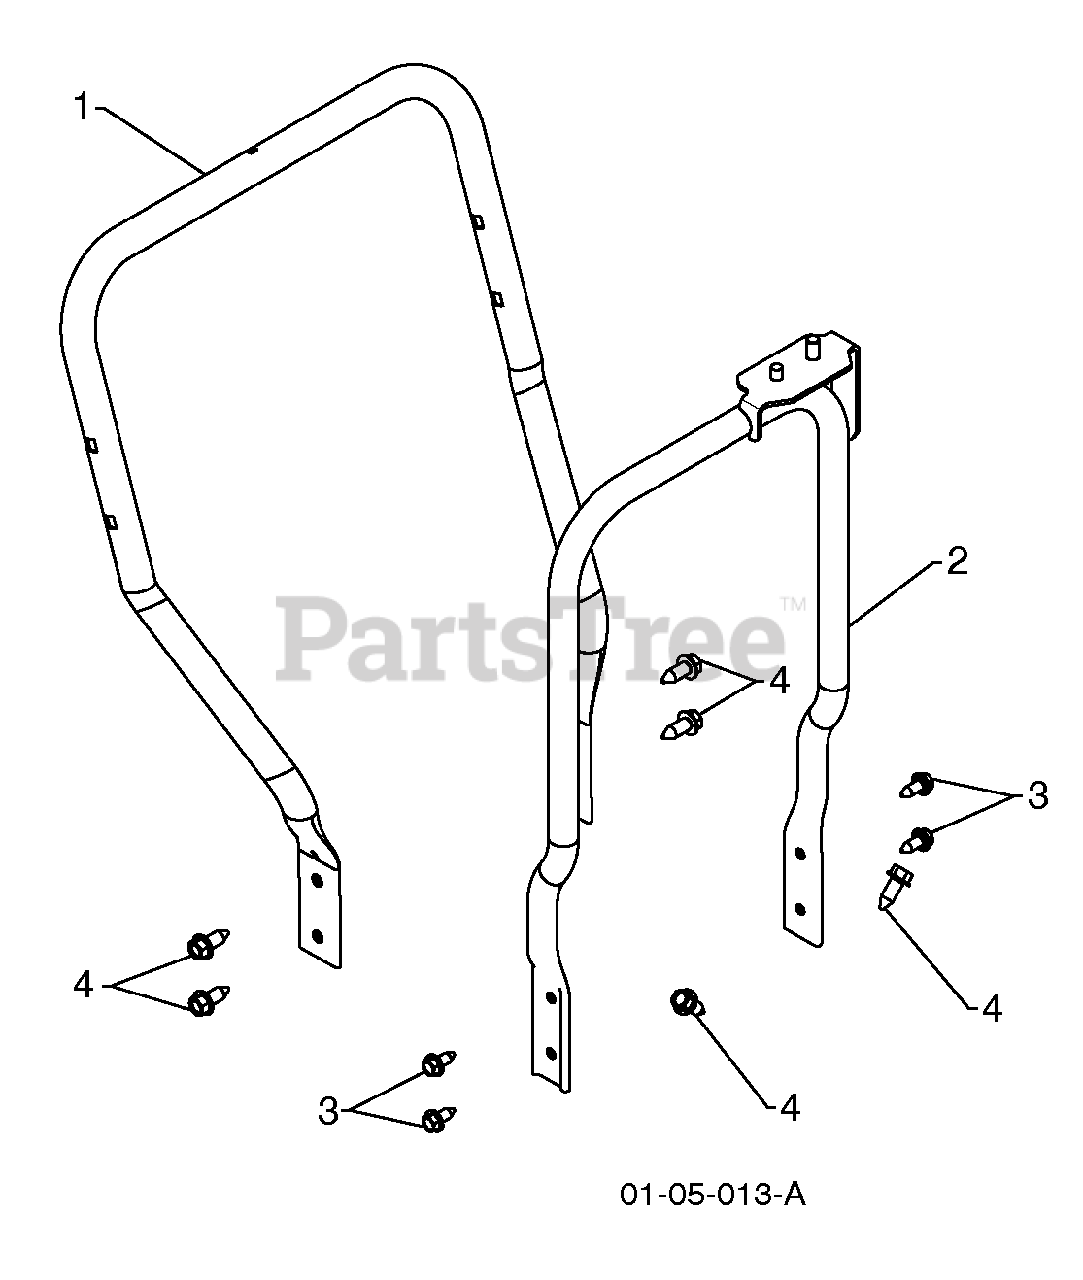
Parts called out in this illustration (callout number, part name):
1	LOWER HANDLE
2	PIVOT SUPPORT WELDMENT
3	SCREW 5/16-18 X .750
4	SCREW 3/8-16 X 1.00
